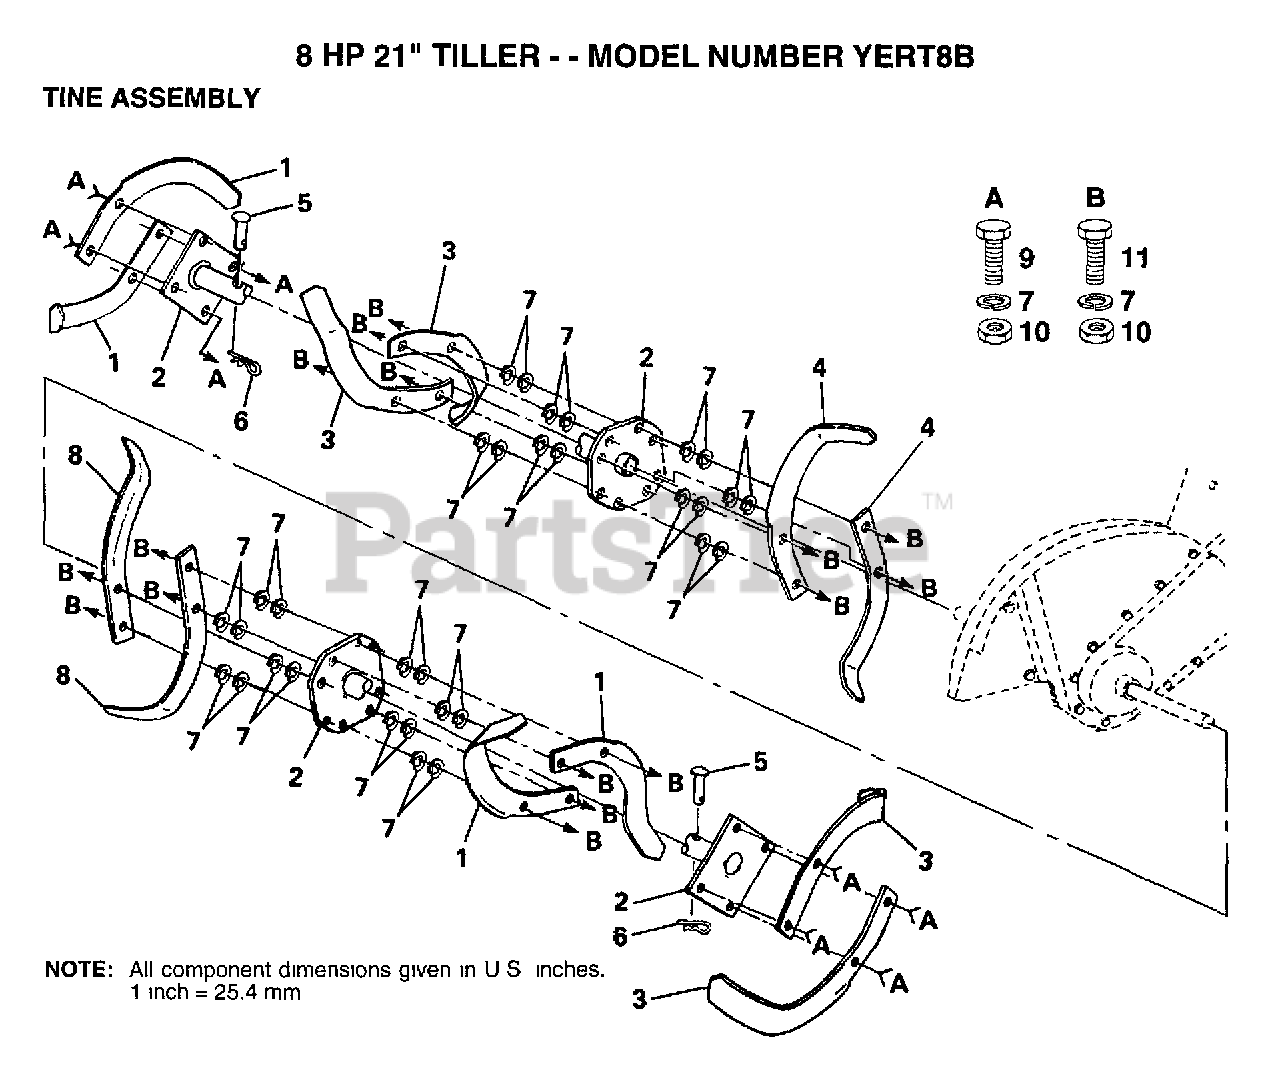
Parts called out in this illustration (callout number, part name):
1	Tine, Outer, L.H.
3	Tine, Outer, R.H.
4	TINE.LH.CRT
5	RIVET.PAN HD.1.75
6	RETAINER.SPRING
7	LOCKWASHER
8	TINE RH CRT
9	BOLT
11	BOLT.3/8-24X1-1/2
